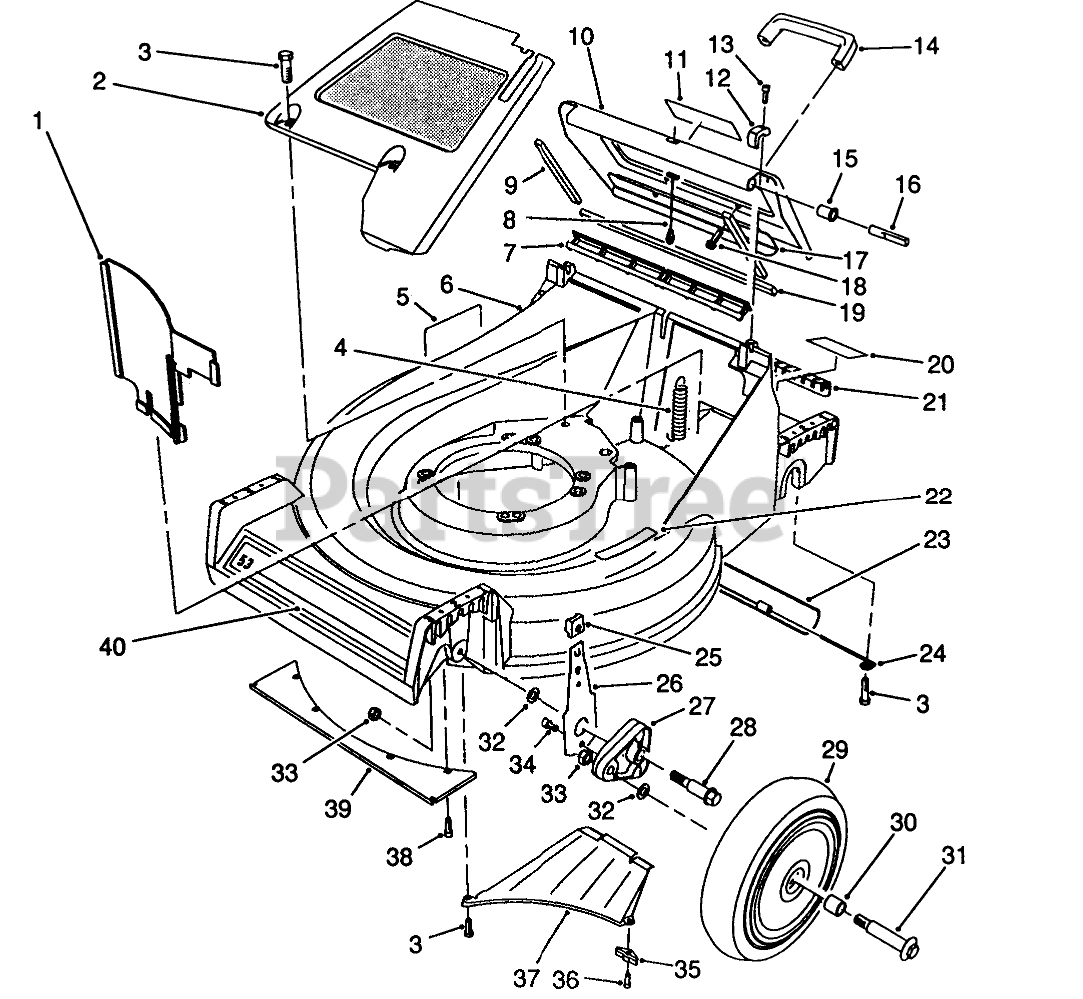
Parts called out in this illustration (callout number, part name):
1	PANEL-VERTICAL
2	PaneI-Screen
3	SCREW-HWHTF
4	EXTENSION-SPRING
5	Decal Danger
6	Housing-53cm (Model 26620C Only) (Incl. Ref. #5 & 22)
7	DOOR SEAL
8	DOOR CABLE
9	DOOR SIDE SEAL
10	Door-Discharge (Incl. Ref. #9, 11 & 19)
11	Decal-Warning
12	HINGE CLAMP
13	SCREW-HSH
14	HANDLE-DOOR
15	DOOR BUSHING
16	HINGE PIN
17	DOOR - BRACE
18	SCREW-HWH
19	DOOR END SEAL
20	Decal-Maintenance
21	ACCESS COVER
22	DECAL - STEP PAD INT'L
23	TRAILING SHIELD
24	LH SHIELD HANGER
25	KNOB-ARM
26	FRONT SPRING ARM ASM
27	ARM-PIVOT, FRONT
28	BOLT-SHOULDER
29	Wheel & Tire Assembly (Incl. Ref. #30)
30	BUSHING
31	WHEEL BOLT
32	WASHER
33	Nut
34	SCREW-HSH, THREAD FORMING
35	Bracket-Discharge
36	SCREW-HWHTF
37	Ramp Discharge
38	SCREW-HWH
39	FRONT GUARD
40	DECAL - 53 CM
